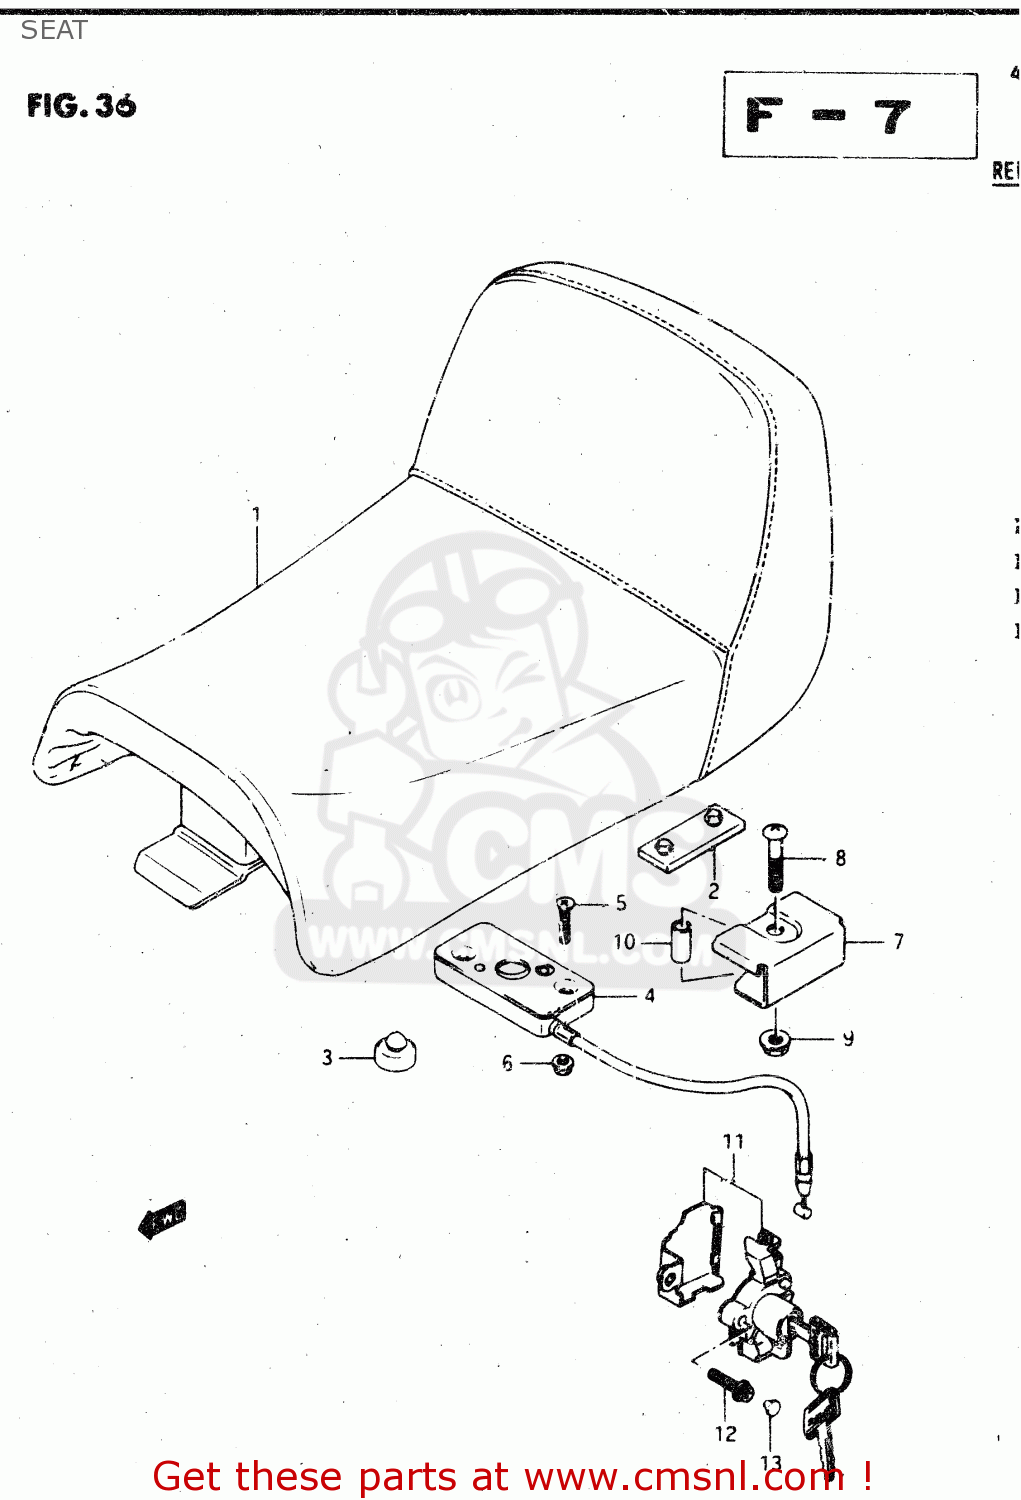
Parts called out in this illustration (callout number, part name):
1	SEAT ASSEMBLY
2	CUSHION
3	CUSHION(11.5X22X20)
4	BRACKET,SEAT SUPPORT,R
5	SCREW
6	NUT
7	PLATE,SEAT CUSHION
8	SCREW
9	NUT
10	SPACER (6.4X9X17.5)
11	LOCK SET
12	PLUG ,6X20
13	CAP(OD:10)
